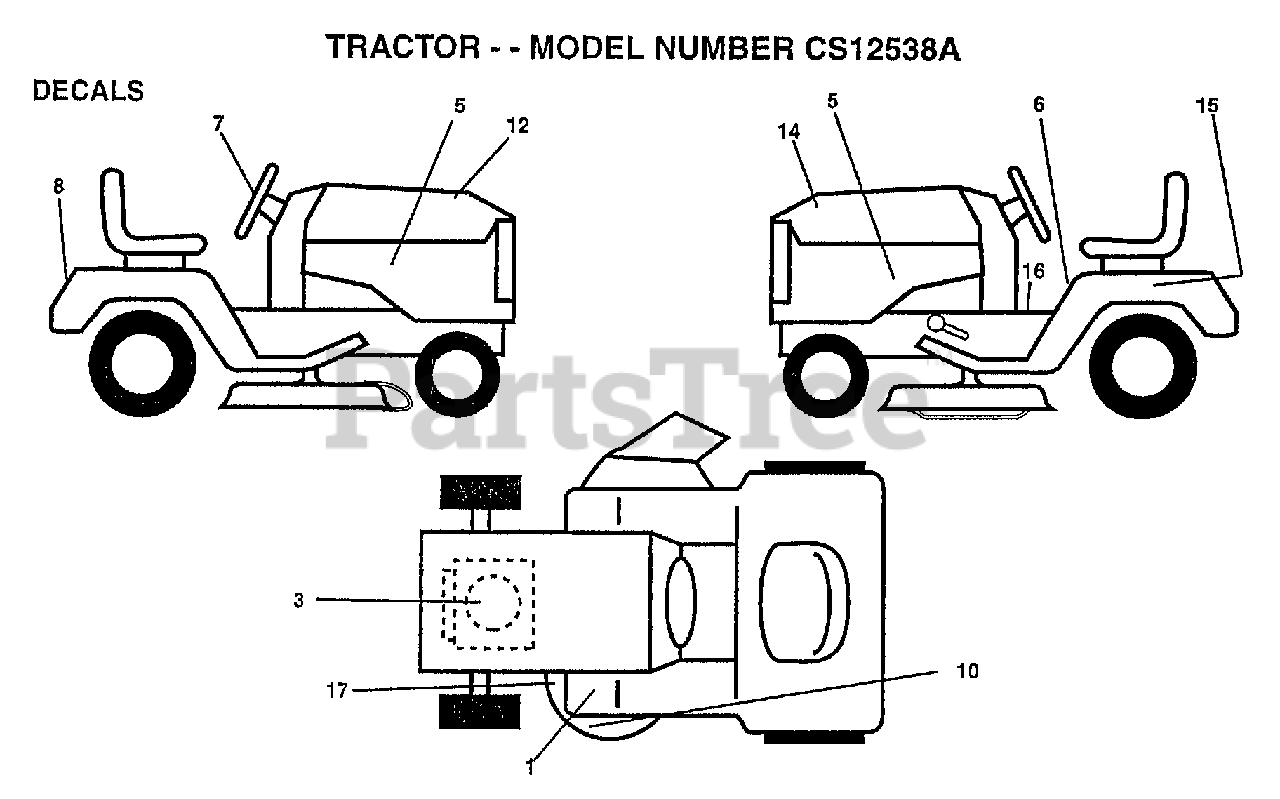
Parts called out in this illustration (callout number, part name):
3	DECAL, ENGINE
5	"DECAL PANEL,SIDE"
6	"DECAL DANGER,FEND"
7	DECAL.INS.WHL.STG
12	DECAL.HD.RH.
14	DECAL.HD.LH.
15	DECAL.BATRY.3-3908
16	"DECAL DASH,OPER."
17	DECAL
